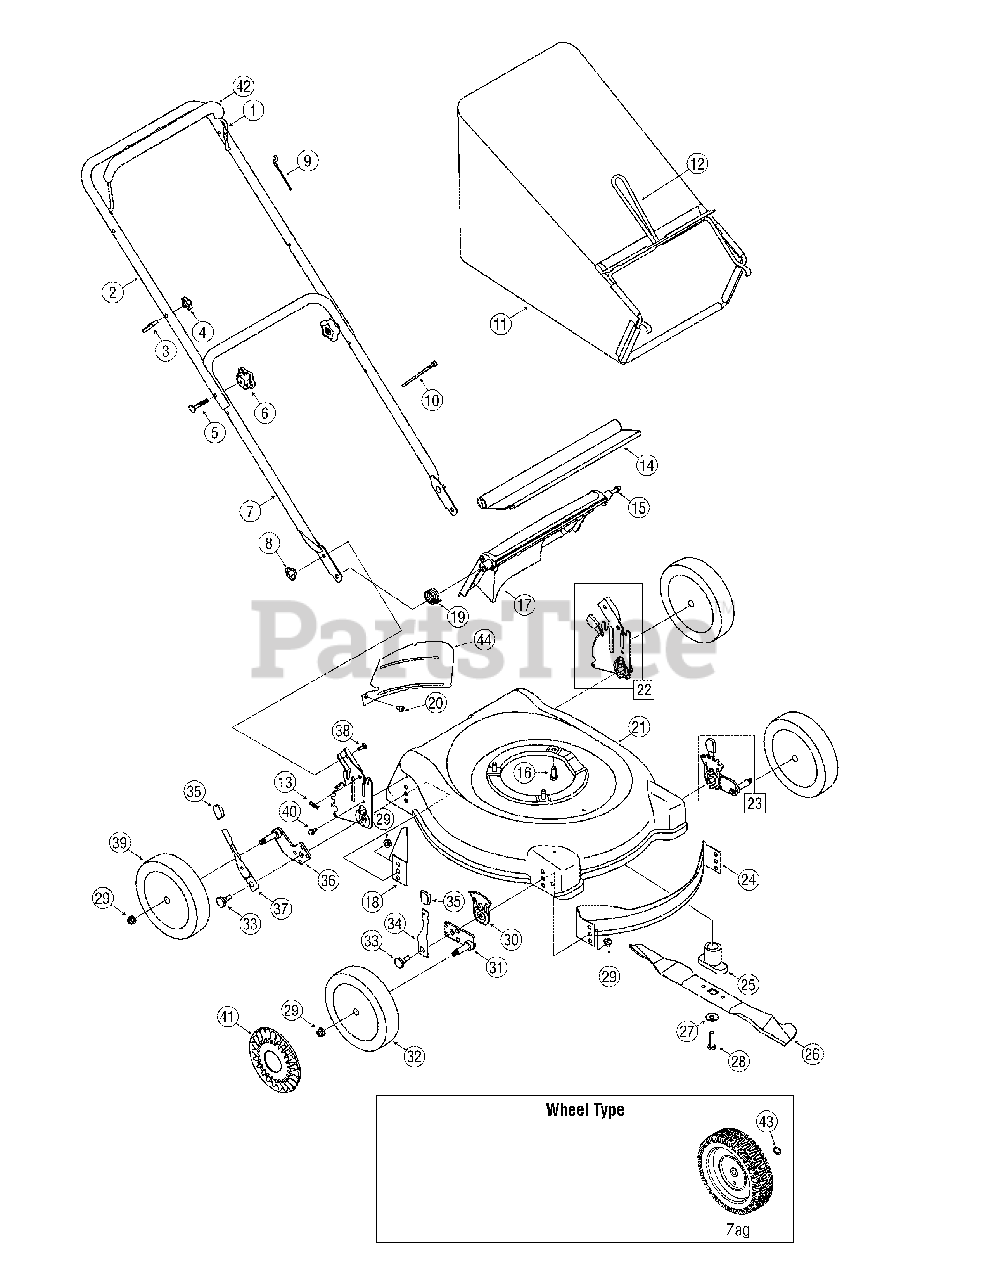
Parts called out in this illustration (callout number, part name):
1	Blade Control
3	Rope Guide
4	Wing Nut, 1/4-20
5	Carriage Bolt, 5/16-18 x 2
6	Hand Star Knob
7	Lower Handle
8	Wing Nut, 1/4-20
9	Control Cable - 40"
10	Cable Tie
11	Grass Bag (MTD Pro)
13	Hairpin Clip
14	Trailshield
15	Rear Door Pivot Rod
16	TT Screw, 3/8-16 x 1
17	Rear Discharge Door
18	Rear Baffle - RH
19	Torsion Spring RH
20	Screw, 1/4-14 x .625
21	Deck 21 inch
22	Handle Bracket Assy - RH
22	Handle Bracket Assy - LH
23	Ht. Adj. Assy. Frt - LH
23	Ht. Adj. Assy. Frt - RH
24	Front Baffle
25	Blade Adapter, 25mm x 1.19
26	Standard Blade
26	Mulch Blade
27	Bell Washer
28	Screw, 3/8-24 x 1.50 (w/25mm Blade Adapter)
29	Flange Lock Nut, 3/8-16
30	Height Adjustment Plate
31	Pivot Arm Assy RH
31	Pivot Arm Assy LH
32	Wheel w/BB, Disc Hub, Zag Tread
33	Shoulder Screw
34	Spring Lever
35	Height Adjustment Knob
36	Pivot Arm Assembly - RH
36	Pivot Arm Assembly - LH
37	Spring Lever
38	Carriage Bolt, 1/4-20
39	Rear Wheel w/BB, Disc Hub, Zag Tread
40	Screw, 1/4-20 x .625
41	Hub Cap
42	Bail Cover
43	Washer, Wave, .510 x .750 x .017
44	Rear Baffle - LH
